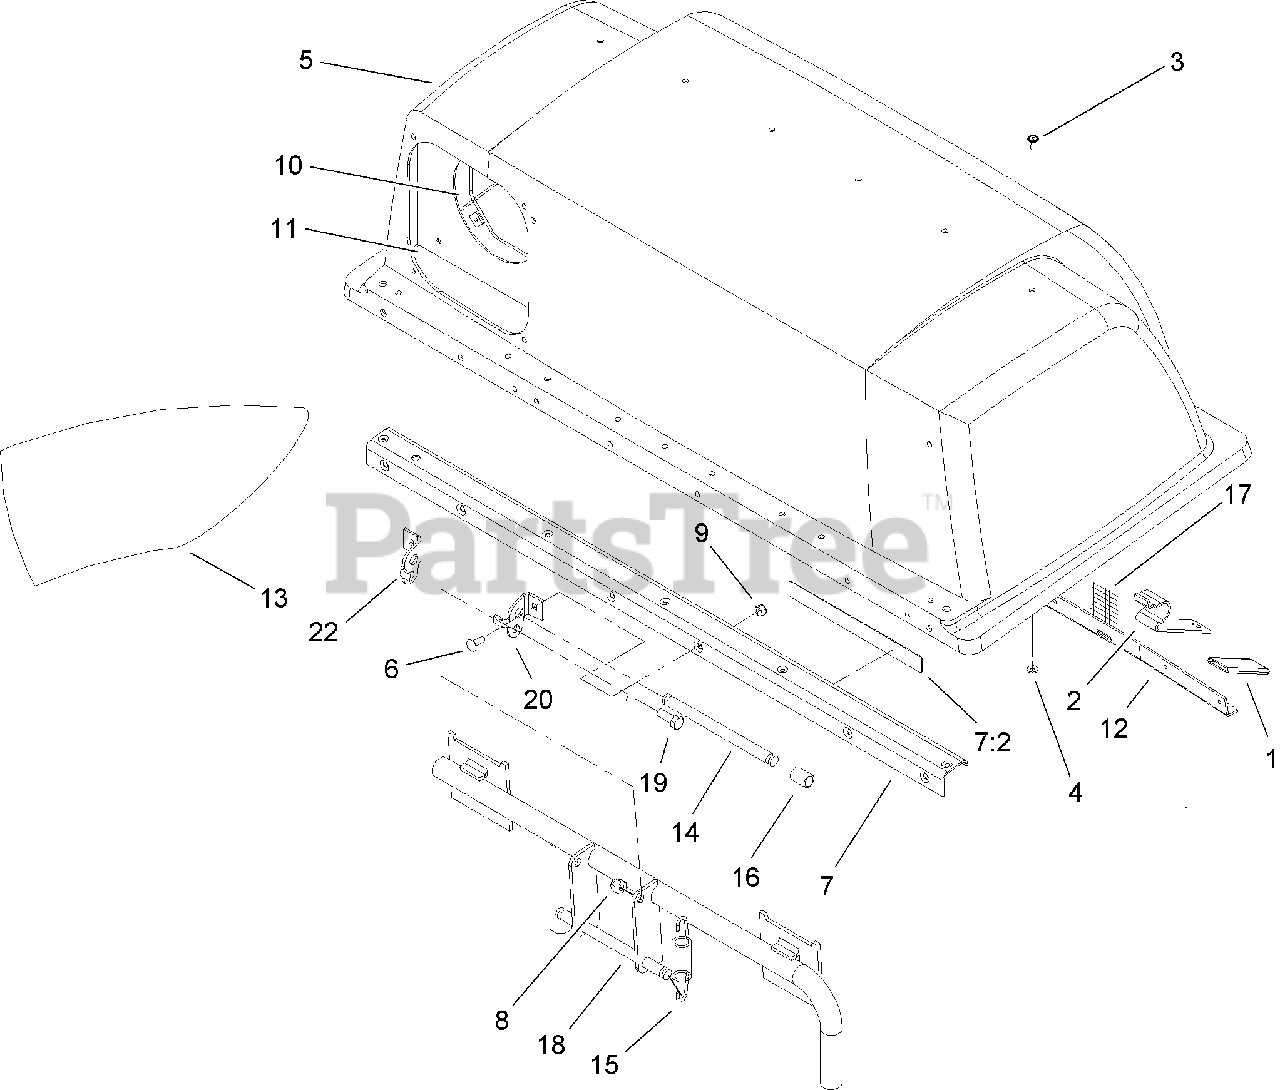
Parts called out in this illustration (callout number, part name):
2	LATCH-BAGGER, TOP
3	RIVET-POP
5	Top-Bagger
6	SCREW-CARR
7	STIFFENER ASM
7:2	DECAL-CAUTION
8	NUT-LOCK, NI
9	NUT-LOCK, NI
10	CLAMP-SEAL
11	SEAL-CHUTE
12	SUPPORT-SCREEN
13	CHUTE-BAGGER
14	PIN-SPRING
15	SPRING-EXTENSION
17	SCREEN-BAGGER
18	FRAME ASM
19	SCREW-HH
20	BRACKET-HINGE, LH
22	BRACKET-HINGE, RH
